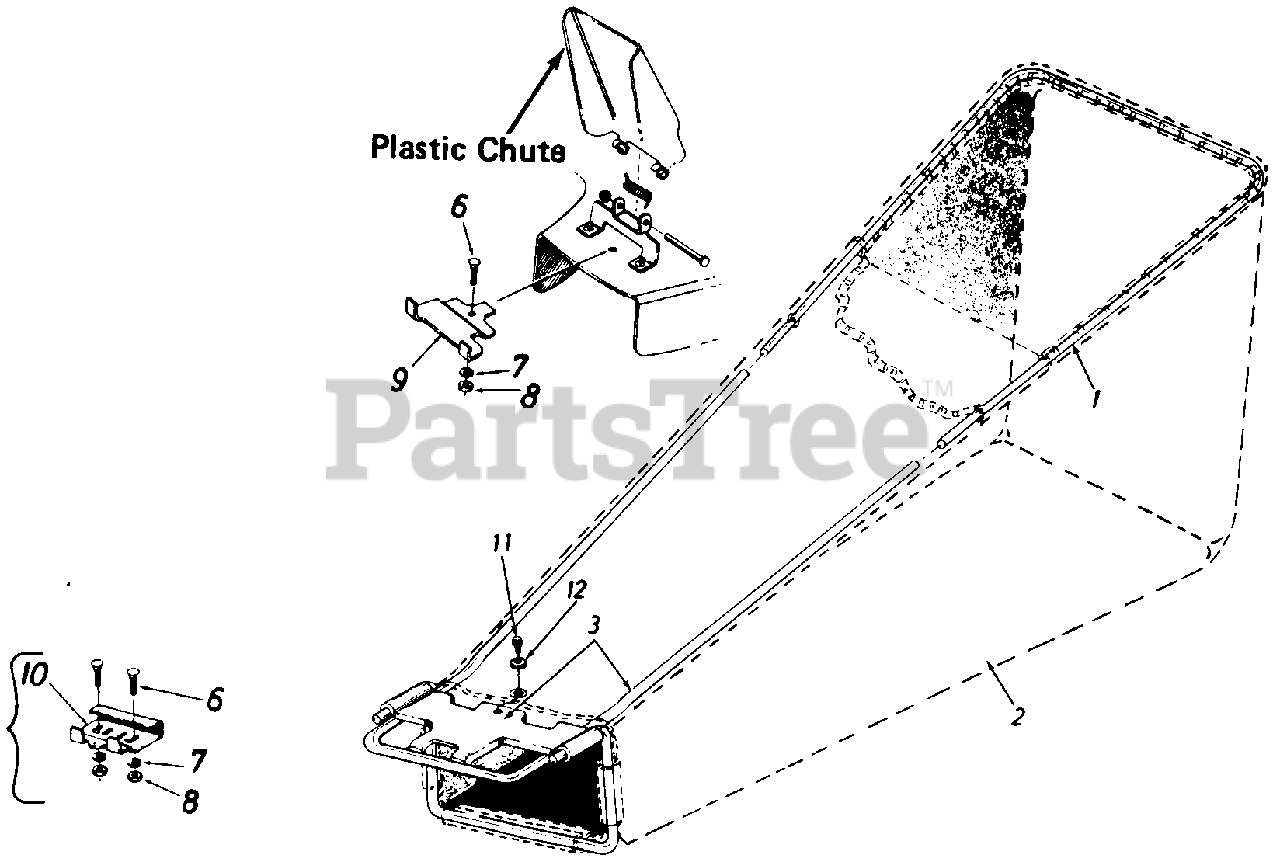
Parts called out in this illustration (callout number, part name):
2	Grass Catcher Bag
3	Frame-Lower
6	Carriage Bolt
7	Lock Washer 1/4" I.D.
8	Hex Nut 1/4-20 Thd.
9	Adapter Plate
10	Adapter Plate
11	Self-Tap Scr. 1/4" x 1/2" Lg.
12	Bell-Wash. 1/4" I.D.
